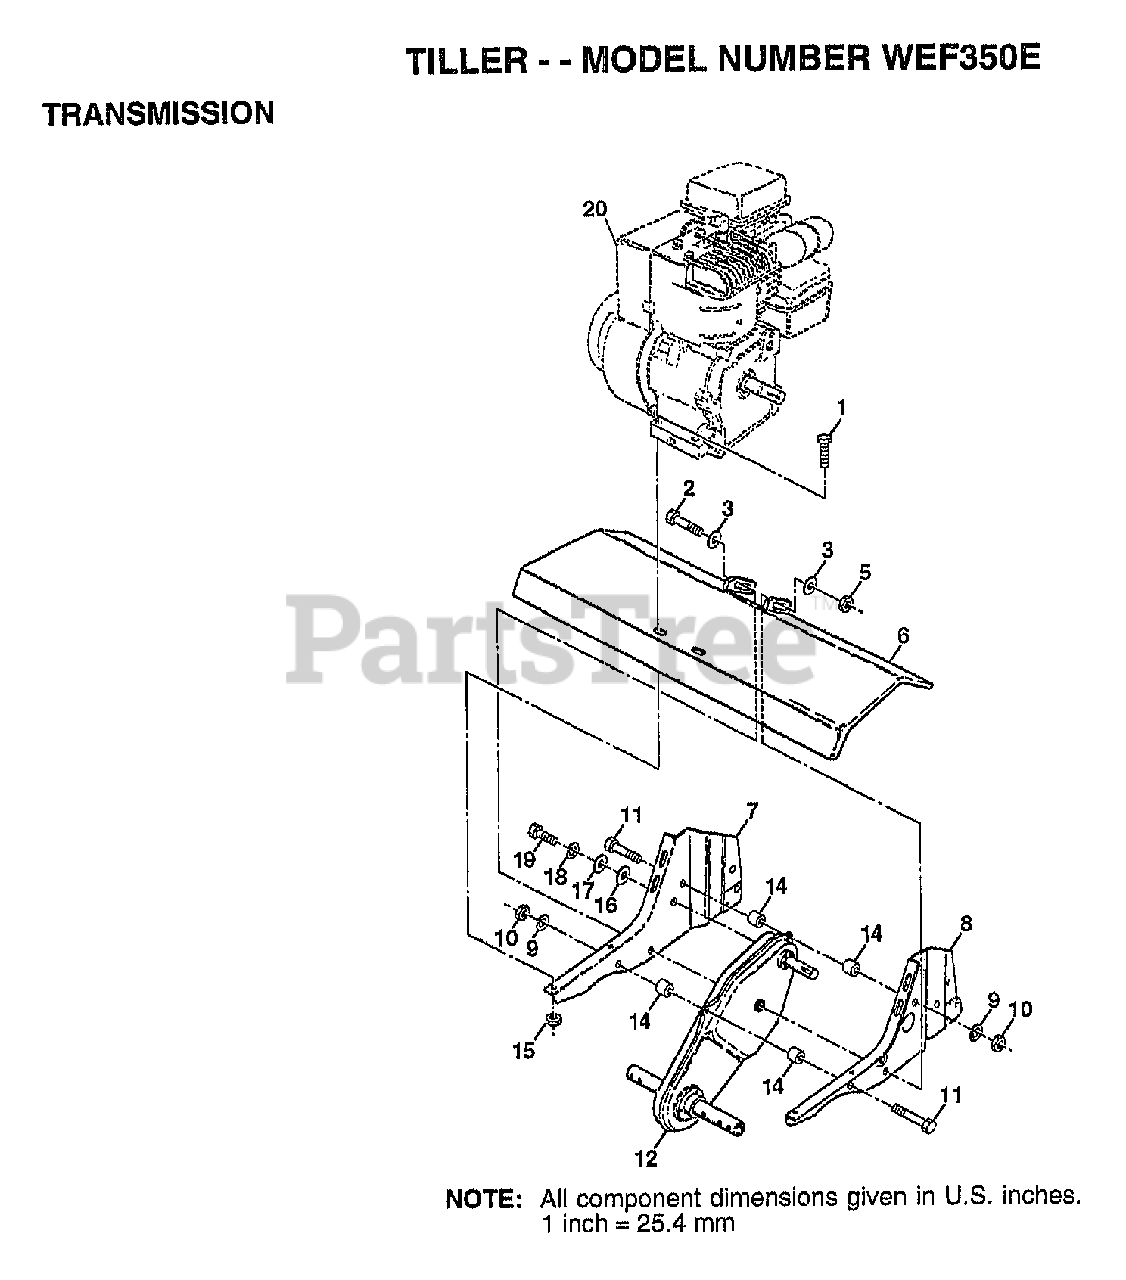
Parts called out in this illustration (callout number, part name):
1	BOLT.HEX.5/16-1.5
2	BOLT HEX 3/8-16
3	WASHER
5	NUT
6	SHIELD.PNT.TINE
7	BRACKET.ENGINE.RH
8	BRKT.ENGINE.LH
9	LOCKWASHER
10	NUT.HEX.5/16-18
14	SPLIT SPACER RT
16	WASHER
17	WASHER
18	LOCKWASHER
19	BOLT
